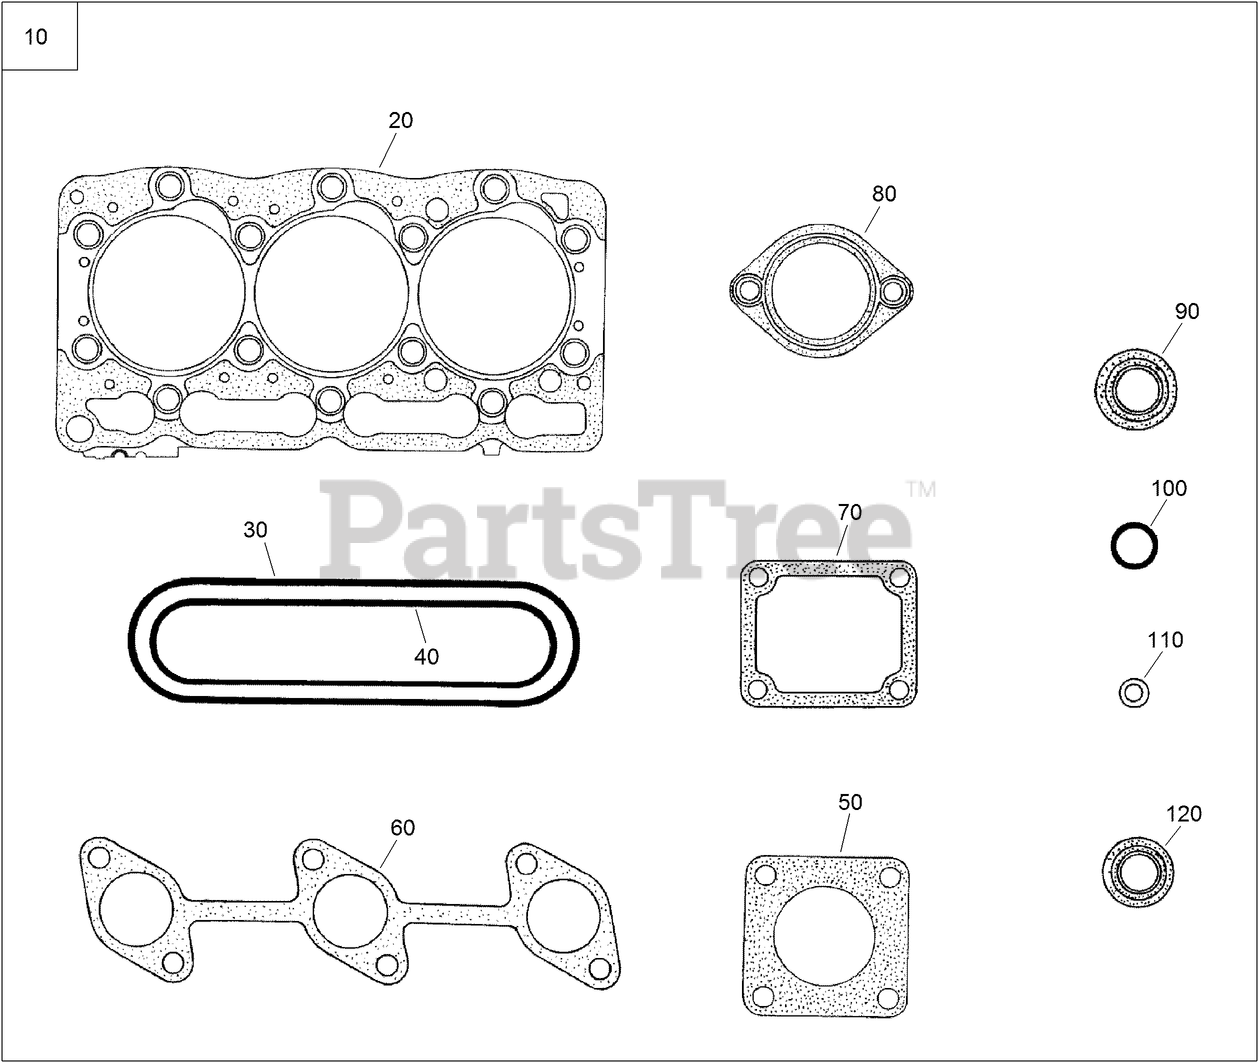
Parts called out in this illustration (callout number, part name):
10	UPPER GASKET KIT
20	GASKET-HEAD, CYLINDER
30	GASKET-COVER, HEAD
40	GASKET-MANIFOLD, INLET
50	GASKET-MUFFLER
60	GASKET-MANIFOLD, EXHAUST
70	GASKET-FLANGE, WATER
80	GASKET-THERMOSTAT
90	SEAL-HEAT
100	O-RING
110	GASKET
120	SEAL-STEM, VALVE
